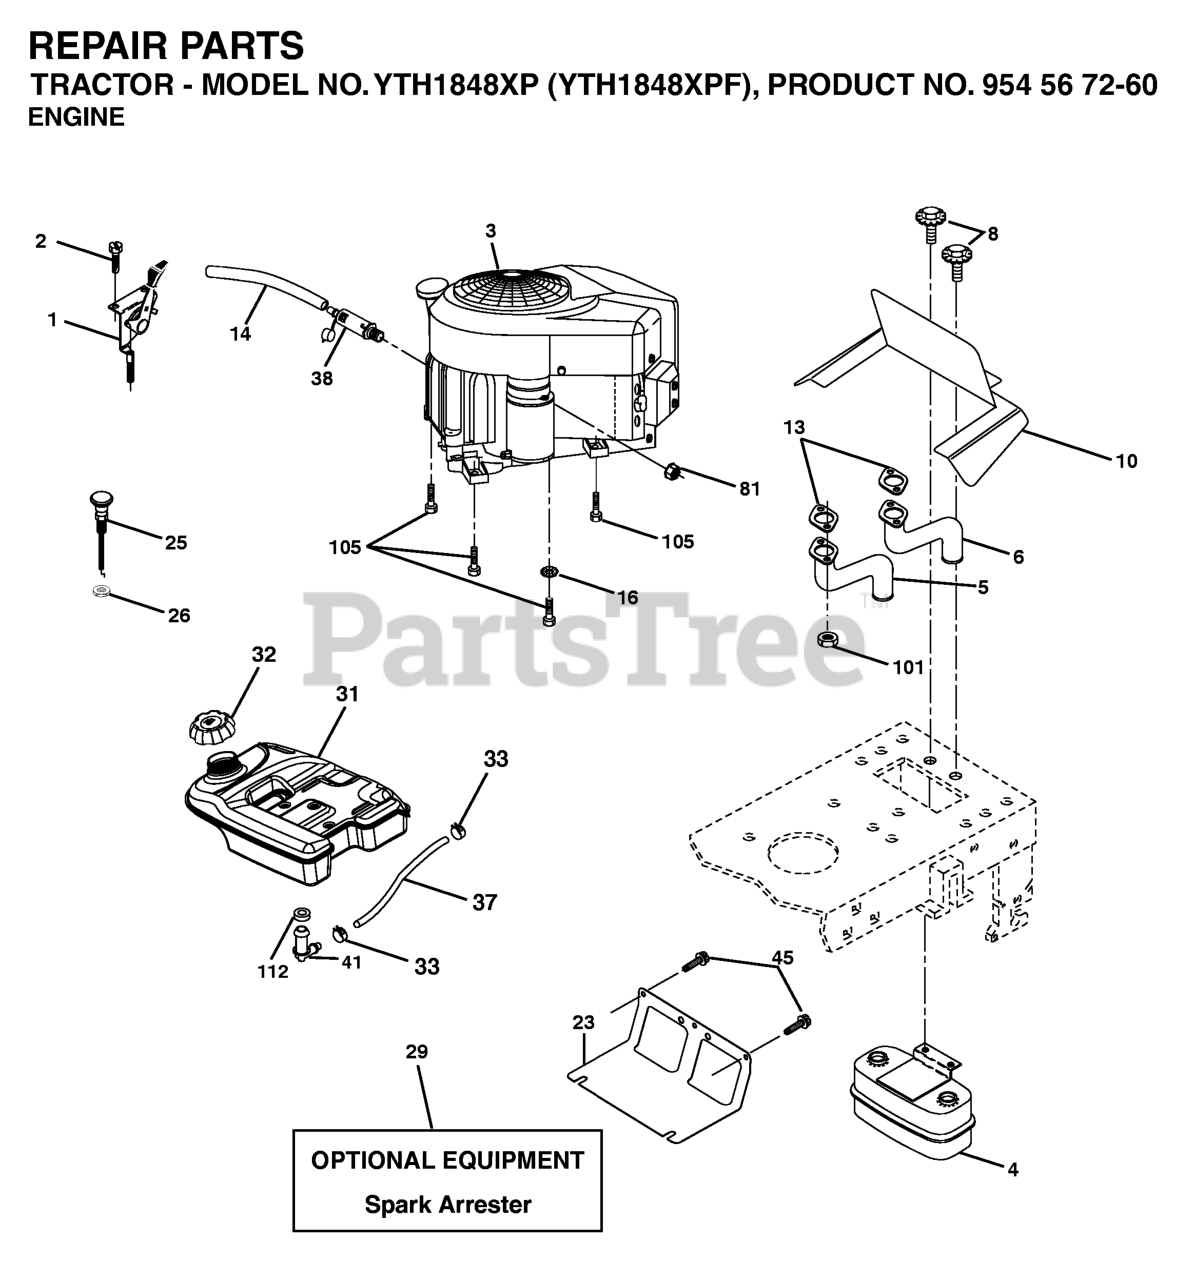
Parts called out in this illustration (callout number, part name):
1	CONTROL, THROTTLE
2	SCREW
4	MUFFLER.TWIN.CYL.LOW.TONE
5	EXHAUST.TUBE.LH.KAWASAKI.
6	EXHAUST.TUBE.RH.KAWASAKI.
8	BOLT.5/16-18UNCX3/4 W/SEMS.BLK
10	RP SHIELD HEAT MUFFLER
14	TUBE, DRAIN OIL ASM.
16	LOCKWASHER
23	SHIELD.BROWNING.DBR.GUARD
25	CHOKE CONTROL
26	Nut Keps 3/8 - 24 UNF
29	KIT.SPARK ARRESTOR 794945 B&S
31	4.0 REAR FUEL TANK
32	TANK CAP
33	HOSE CLAMP
37	REPL BY 532 00 85-43
41	STEM FUEL TANK
45	SCREW, 3/8-16X3/4
81	NUT
101	FLANGE NUT
105	SCREW 3/8-16X1
112	BUSHING OUTLET T
